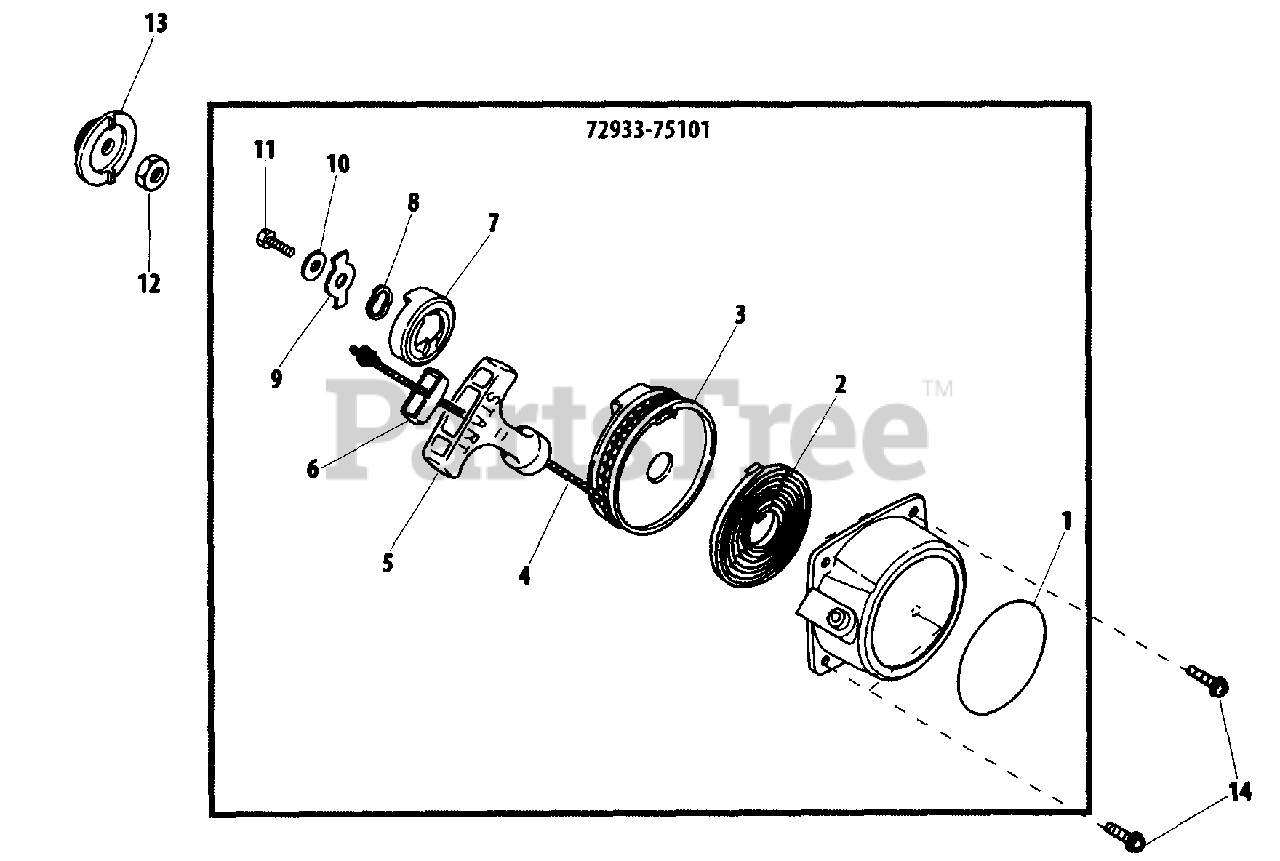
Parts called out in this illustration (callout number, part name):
1	LABEL, RECOIL STARTER
2	SPRING, RECOIL
3	REEL, ROPE
4	ROPE, STARTER
5	HANDLE
6	RETAINER, ROPE
7	RATCHET
8	WASHER, WAVE
9	RETAINER
10	WASHER 5 MM
11	SCREW 5 MM
12	NUT M8×1
13	PULLEY, STARTER
14	SCREW
